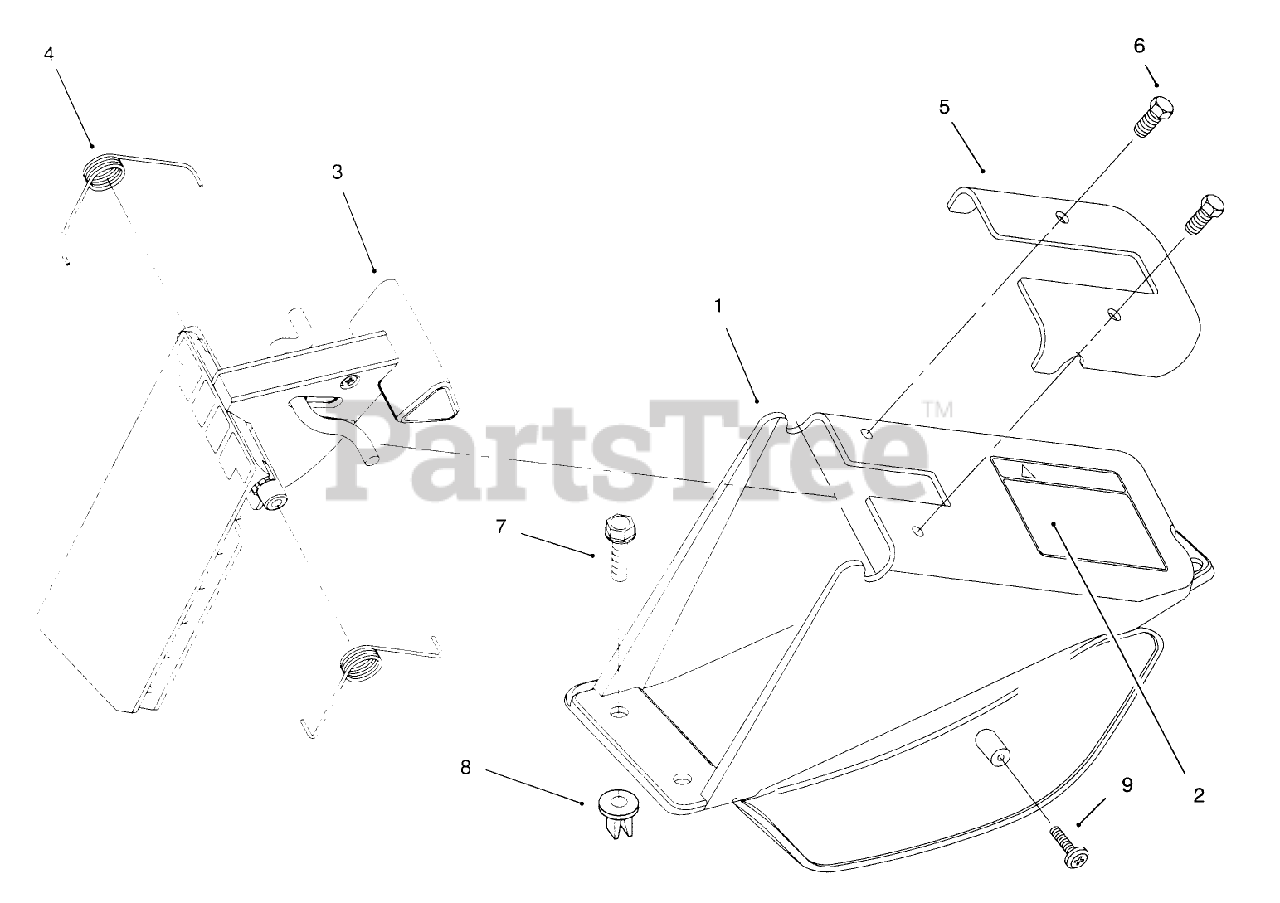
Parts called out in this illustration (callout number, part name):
2	DECAL - CAUTION DOOR
3	ASM - DISCHARGE DOOR
4	SPRING-DOOR, RH
6	SCREW-PLASTITE
7	SCREW-HWH
9	SCREW-PPH
